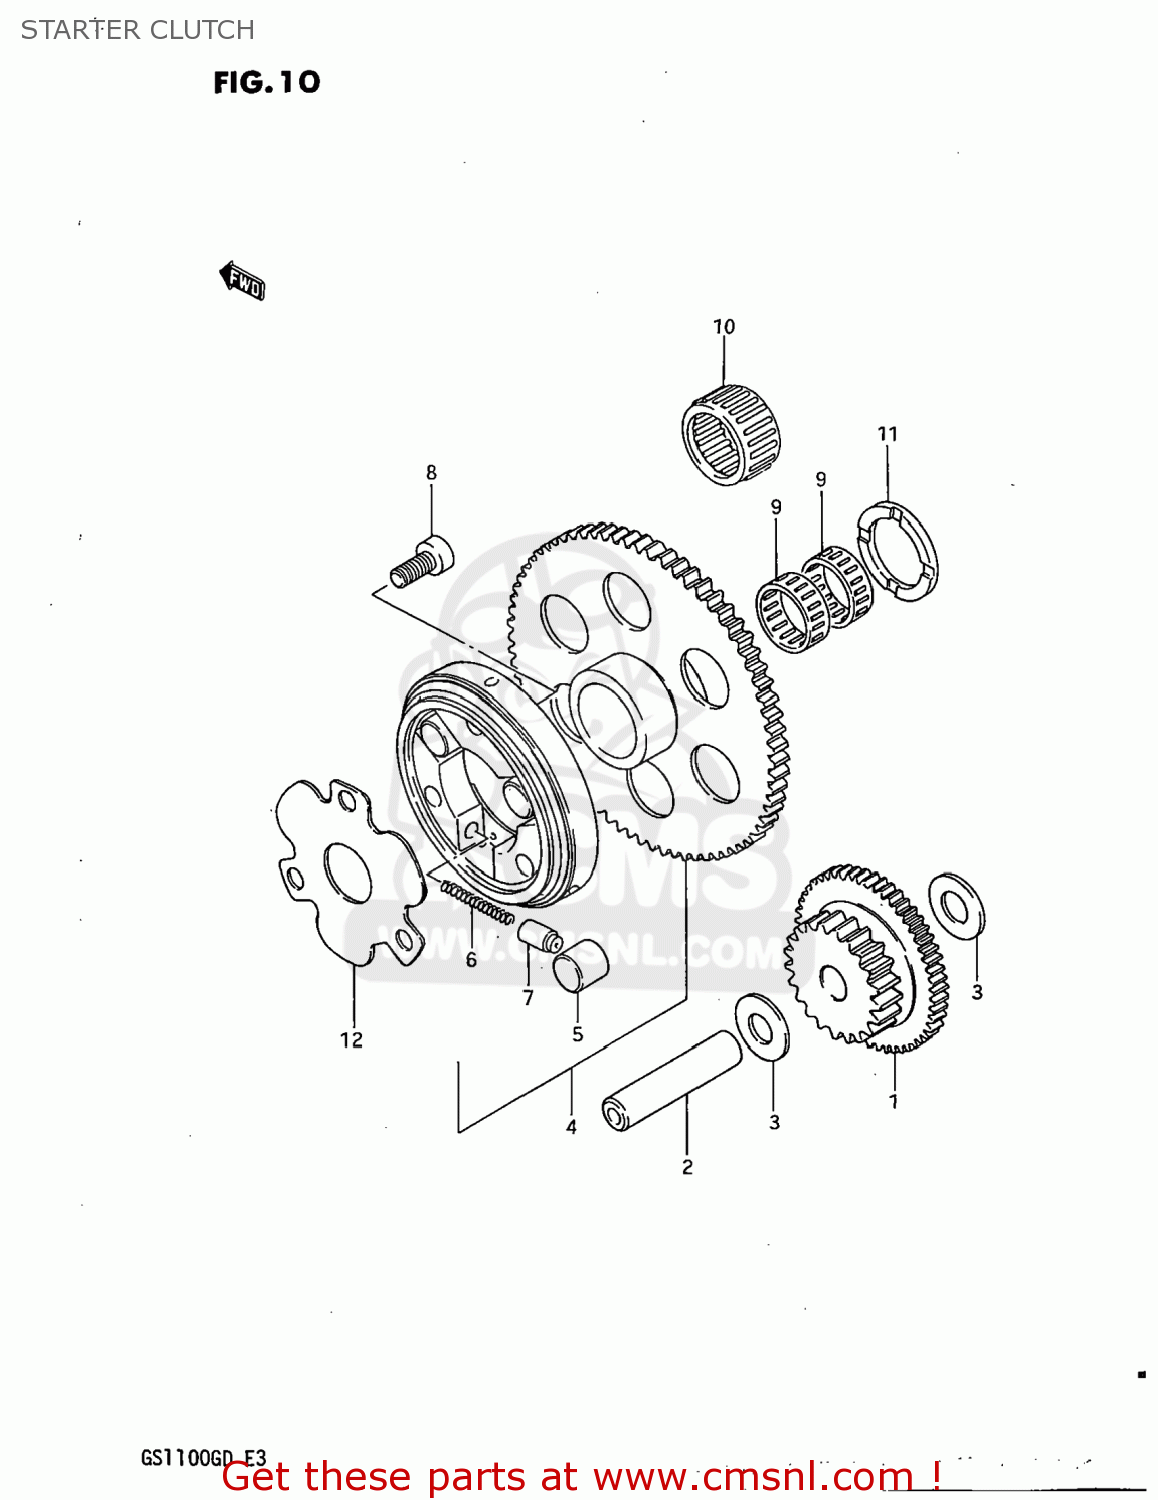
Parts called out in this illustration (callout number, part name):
1	GEAR,STARTER IDLE
2	PIN(7.4X13X56)
3	WASHER(13.3X25X0.85)
4	CLUTCH SET,STARTER
5	PIN(14X13)
6	SPRING
7	PIECE,PUSH
8	BOLT
9	BEARING
10	ROLLER BEARING (25X31X2
11	WASHER(25X38X2.5)
12	SHIM,STARTER CLUTCH HUB
